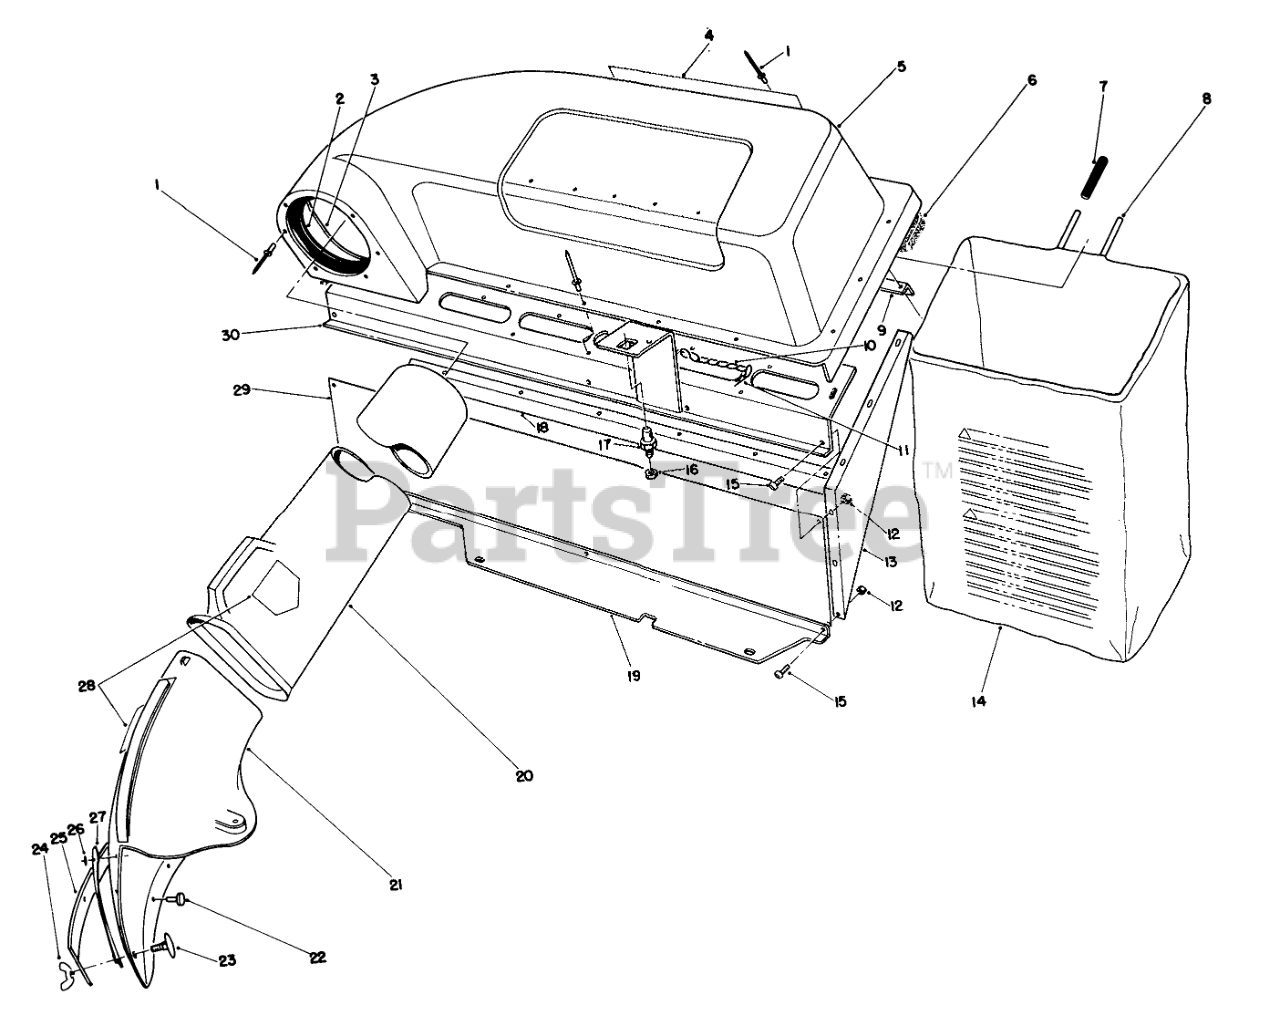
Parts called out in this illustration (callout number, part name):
1	RIVET-POP
2	EXH DUCT GASKET
3	Ring-Gasket
4	Decal-Twin Bagger
5	Cover
6	FOAM SEAL
7	GRIP-HANDLE, BAG
8	BAG FRAME
9	BAG FRAME BRKT
10	6-LINK CHAIN W/HOOK
11	HAIRPIN COTTER
12	NUT-LOCK, NI
13	Plate-Side
15	SCREW-PPH
16	NUT-LOCK, NI
17	Pin-Mounting
18	BAG SUPPORT CHANNEL
19	BASE BRKT "B"
20	Duct Assembly (Incl. Ref. #2)
21	Chute Assembly (Incl. Ref. #22, 25-28)
22	RIVET 3/16 X 7/16
23	STEP BOLT
24	NUT-WING
25	Strap
26	WASHER-PLAIN
27	Shield
28	DECAL-DANGER
29	Shield-Muffler
30	BAFFLE WA "B"
